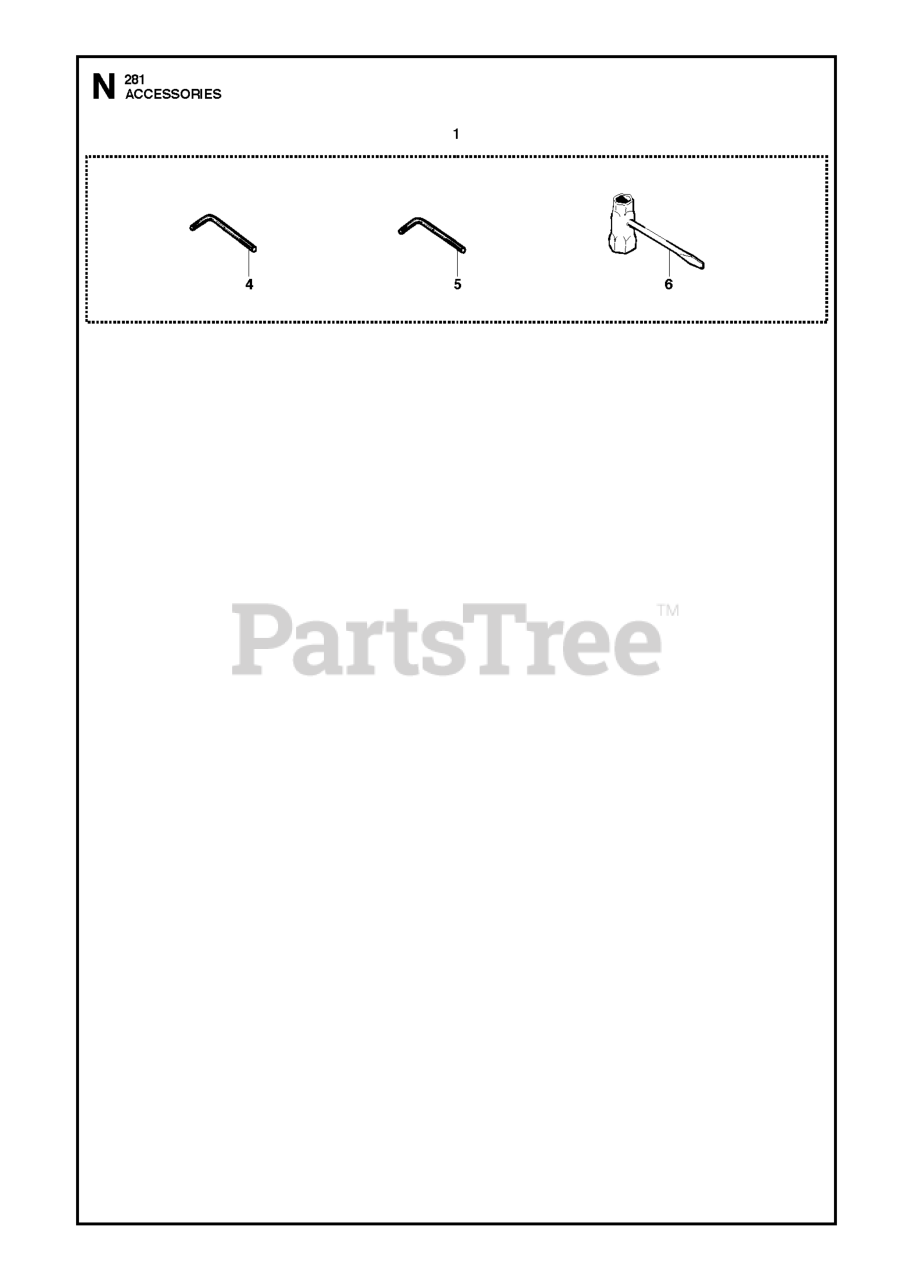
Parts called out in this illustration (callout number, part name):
1	TOOL KIT
4	L-SPANNER
5	L-SPANNER
6	COMBI TOOL
7	Grease Gun
8	GREASE
